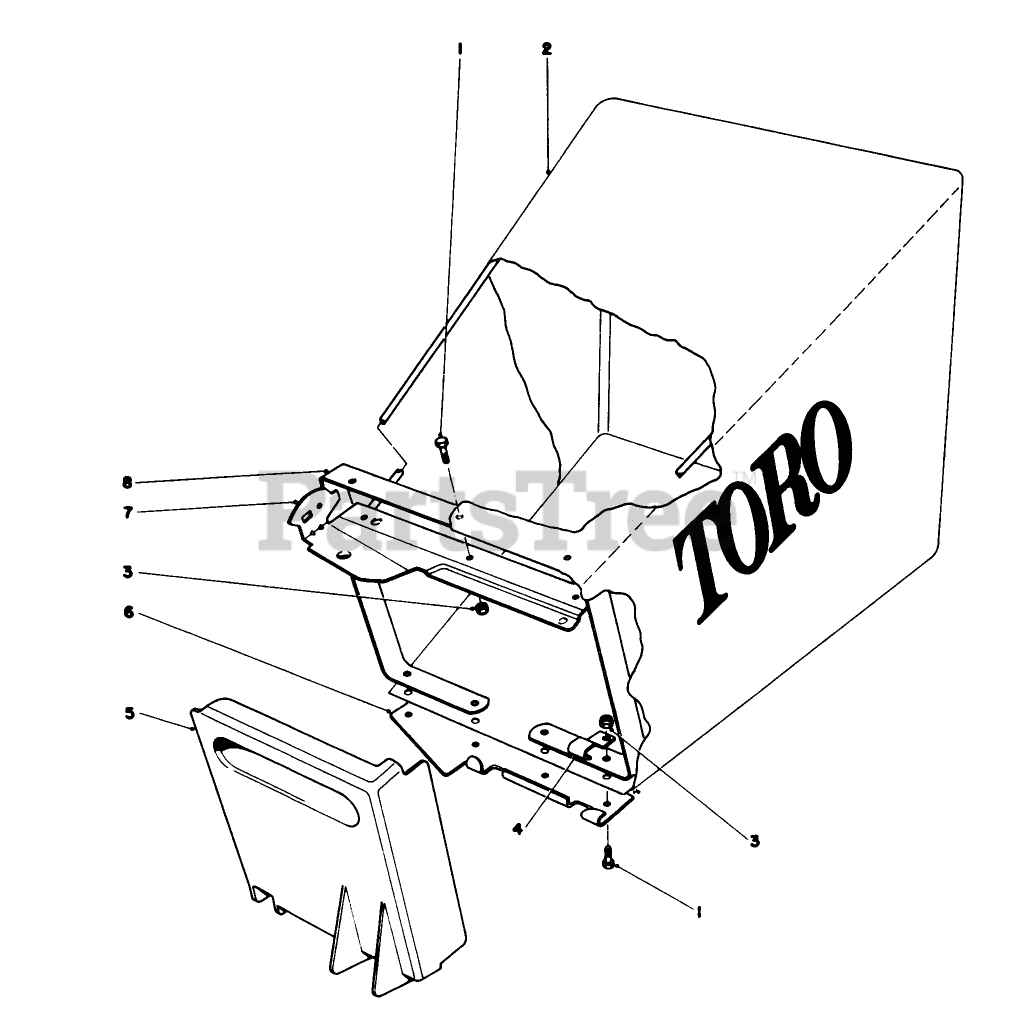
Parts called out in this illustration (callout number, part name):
1	SCREW-HWH
2	REPLACMNT BAG 44-0530
3	NUT/WASHER
4	SUPPORT BRACKET
5	BAG DOOR
6	DOOR BRACKET
7	BAG FRAME WA
8	LOWER BAG FRAME
